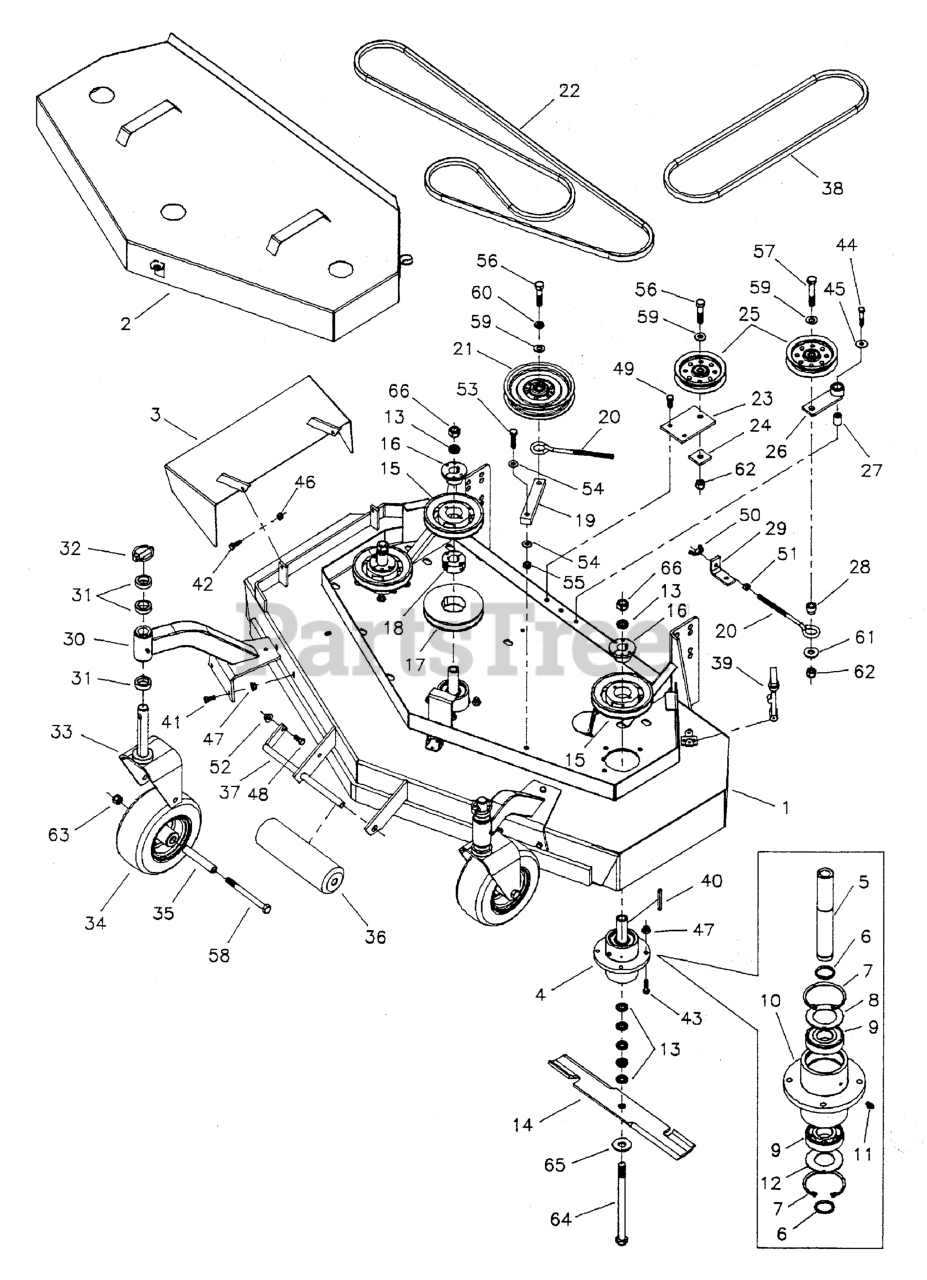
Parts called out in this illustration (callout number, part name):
1	DECK SHELL W/DECALS, 52" - DD52
2	52" DECK GUARD
3	CHUTE, DISCHARGE WELDMENT
4	SPINDLE ASSEMBLY, Complete
5	SPINDLE SHAFT
6	SNAP RING, External
7	SNAP RING, Internal
8	SPINDLE WASHER, Top
9	BEARING
10	SPINDLE HOUSING
11	GREASE FITTING
12	SPINDLE WASHER, Bottom
13	SPACER, .63 x 1.06 x .23
14	MOWER BLADE, 18"
15	PULLEY, Spindle
16	BUSHING, Tapered Hub
17	PULLEY, Taper Lock
18	BUSHING, Taper Lock
19	ARM, Idler
20	EYEBOLT, 3/8" x 8"
21	PULLEY, Backside Idler
22	BELT, Blade Spindle
23	BRACKET, Idler Pulley
24	SPACER, Idler Pulley
25	PULLEY, Idler
26	ARM, Idler
27	SPACER, .32 x .75 x 1.06
28	INSERT, Bearing Shoulder
29	SPRING ANCHOR
30	CASTER MOUNT, Complete
30	BUSHING, FLANGE
30	GREASE FITTING
31	SPACER, 1.02 x 1.56 x .50
32	PIN, Lynch
33	YOKE, Caster
34	WHEEL & TIRE ASSEMBLY, White, 9 x 3.5 x 4, Complete
35	AXLE, Caster Wheel
36	ROLLER
38	BELT, Deck Drive
39	RUBBER LATCH
40	KEY, 1/4 SQ. X 2-1/2
41	BOLT, 5/16-18 X 3/4 GD5
42	BOLT, 5/16-18 X 1 GD5 YZ
43	BOLT, 5/16-18 x 1-1/4
44	BOLT, 5/16-18 x 1-3/4
45	WASHER, 5/16" Fender
46	NUT, 5/16-18 Hex Nylon Lock
47	NUT, 5/16-18 HEX SERRATED FLANGE (LARGE)
48	BOLT, 3/8-16 X 3/4" GD5 CZ
49	BOLT, 3/8-16 X 1" GD5 CZ
50	NUT, 3/8-16 Wing Nylon Lock
51	NUT, 3/8-16 Hex
52	NUT, 3/8-16 Hex Serrated Flange
53	BOLT, 7/16-20 X 1-3/4" GD.5
54	WASHER, 7/16" SAE
55	NUT, 7/16-20 Hex Nylon Lock
56	BOLT, 1/2-20 X 2-1/4 GD5 CZ
57	BOLT, 1/2-20 x 3
58	BOLT, 1/2-13 x 5-1/2
59	WASHER, 1/2 SAE
60	WASHER, 1/2" USS
61	NUT, 1/2-13 HEX NYLON LOCK
62	NUT, Hex, Nylon Lock, 1/2-20
63	NUT, 1/2-13 HEX NYLON LOCK
64	BOLT, 5/8-11 x 9-1/2
65	WASHER, 5/8" USS
66	NUT, 5/8-11 Hex
